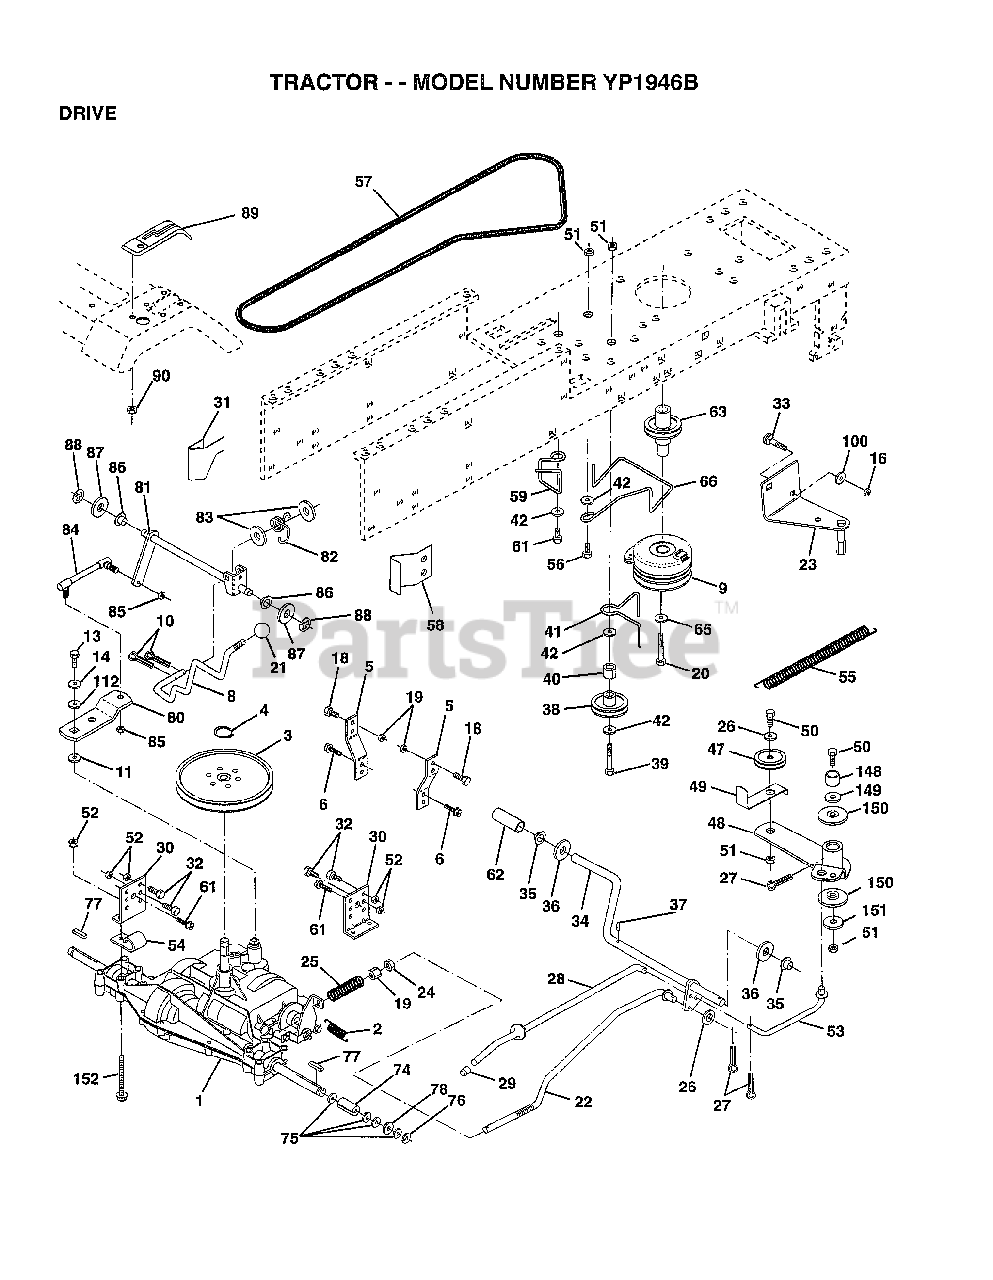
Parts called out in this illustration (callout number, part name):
1	TRANSAXLE ASM
2	SPRING.BRAKE.RETU
3	PULLEY TRANS
5	STRAP TORQUE
6	SCREW
8	ROD SHIFT FEND YT
9	CLUTCH.ELECTRIC
10	PIN COTTER 1/8
11	WASH-SHFT PLT LT
13	BOLT.1/4-28.W/PAT
14	LOCKWASHER
16	NUT
18	BOLT
19	NUT
20	BOLT.7/16-20X4.25
21	KNOB.DUCKHEAD.1/2
22	BRAKE ROD
23	BRACKET.CLUT.MTG.
24	NUT
25	SPRING ROD LT
26	WASHER
27	COTTER PIN
28	ROD.BRAKE.PARK.LT
29	PLUNGER CAP T
30	TRANSAXLE MTG BKT
31	"KEEPER,BELT LH T"
32	BOLT
33	BOLT
34	SHAFT ASM-PEDAL F
35	NYLON BEARING
36	WASHER LT
38	PULLEY.IDLER.FLAT
39	BOLT
40	SPACER T
42	WASHER
48	BELLCRANK.CLUTCH
49	RETAIN BELT
53	"LINK, CLUTCH T"
54	CLIP T
55	"SPRING, RETURN LT"
57	"V-BELT,95.3"
58	"KEEPER,BELT RH T"
59	KEEPER BELT CNTSP
61	SCREW
62	"COVER,PEDAL"
63	PULLEY.CLUTCH.EVX
65	LOCKWASHER
66	KEEPER-BELT
74	SPACER LT
76	E-RING LT
77	SQUARE KEY
78	WASHER
80	SHAFT ASSY CROSS
81	SHAFT.CROS.20.STR
82	"SPRING,TORSION"
83	WASHER
84	TIE ROD
85	NUT.CNT.LOCK.1/4
86	BUSHING
87	WASHER D
88	KLIP RING
89	CONSOLE SHIFT
90	NUT
100	WASHER M
112	WASHER LT
149	SPACER RETAINER
150	BUSHING.NYLON
151	WASHER
152	BOLT.HX.FLG.5/16
